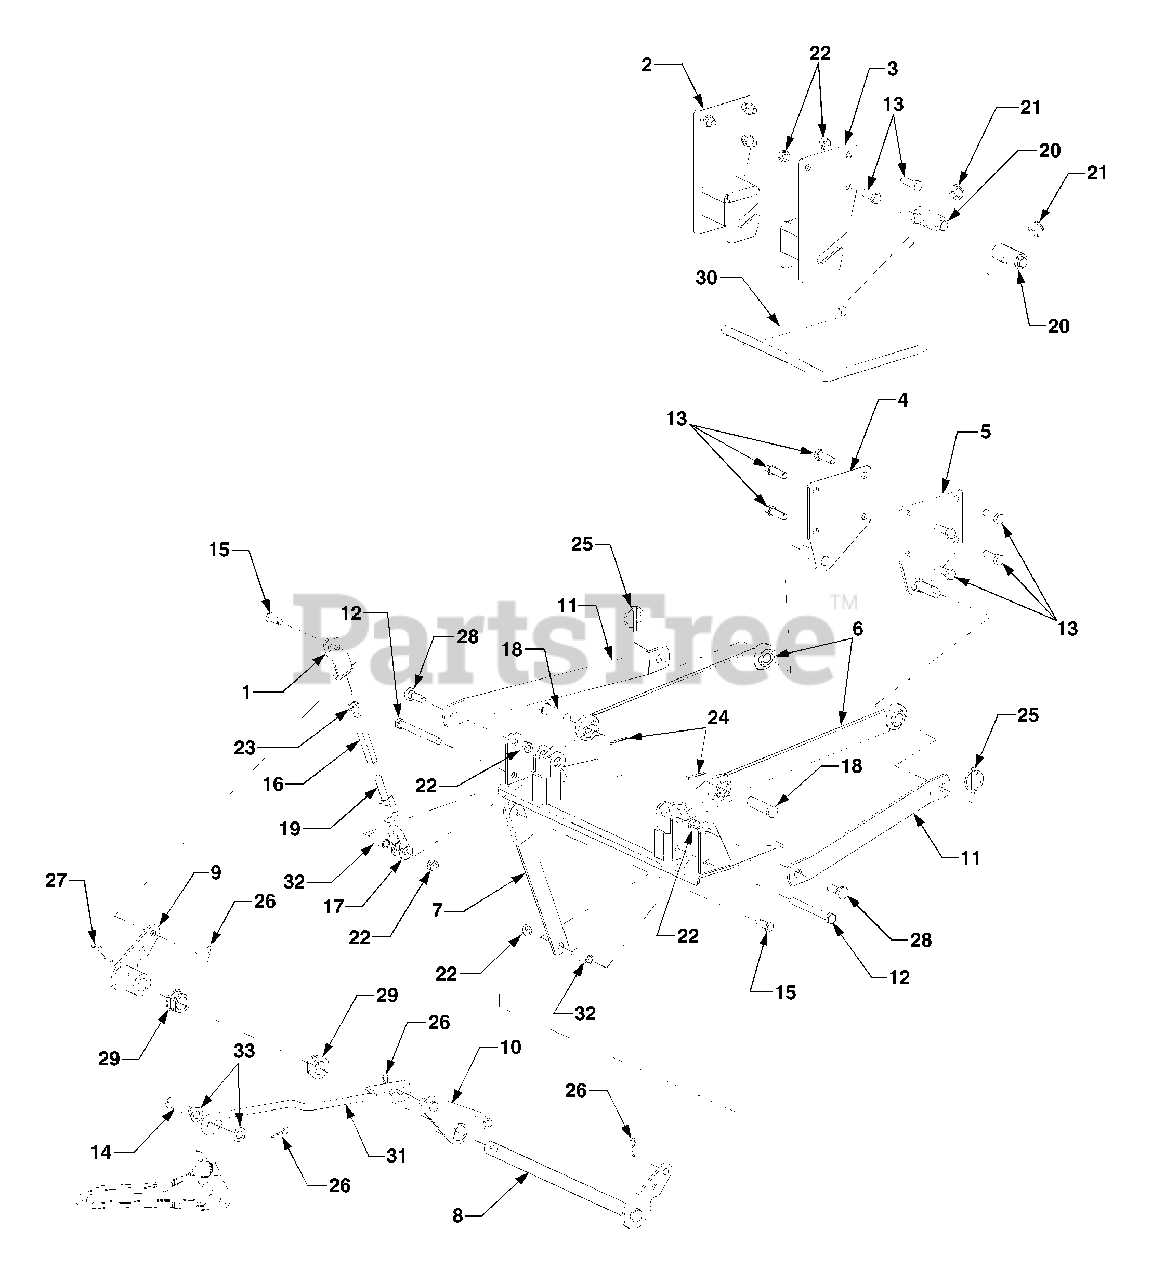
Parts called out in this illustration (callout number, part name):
1	Clevis, Adjustment, 1/2 -13 x 4.76 1
2	Bracket, Front Hanger LH
3	Bracket,, Front Hanger RH
4	Bracket, Rear Hanger LH
5	Bracket, Rear Hanger RH
6	Link, Deck Lift
10	Plate, Lift Crank
11	Brace, Deck Side
12	Screw, Hex Cap, 1/2-13 x 4.5 GR5
13	Screw, Hex Cap, 1/2-13 x 1.5 GR5
14	Pin, Clevis, .625 x 2.4
15	Pin, Clevis, .5 x 1.18
16	Turn Buckle, Hex Adjustment
17	Clevis, Check Chain
18	Pin, Clevis, 3/4 x 2.5
19	Clevis, Chain
20	Pin, Hanger Rod Mounting
21	Nut, Hex Insert Lock, 5/8-11
22	Nut, Hex Center Lock, 1/2-13
23	Nut, Hex Jam, 1/2-13 GR5
24	Pin, Cotter, 3/16 x 1.5
25	Pin, Klik
26	Pin, Internal Cotter
27	Pin, Spirol, 5/16 x 1.75
28	Screw, Shoulder, .625 x.36: 1/2-13
29	Bearing, Flange w/Flats
30	Rod, Front Hanger
31	Rod, Crank Lift
32	Spacer, .51 x .75 x 1.67
33	Washer, Flat, .635 x 1.125 x .09
